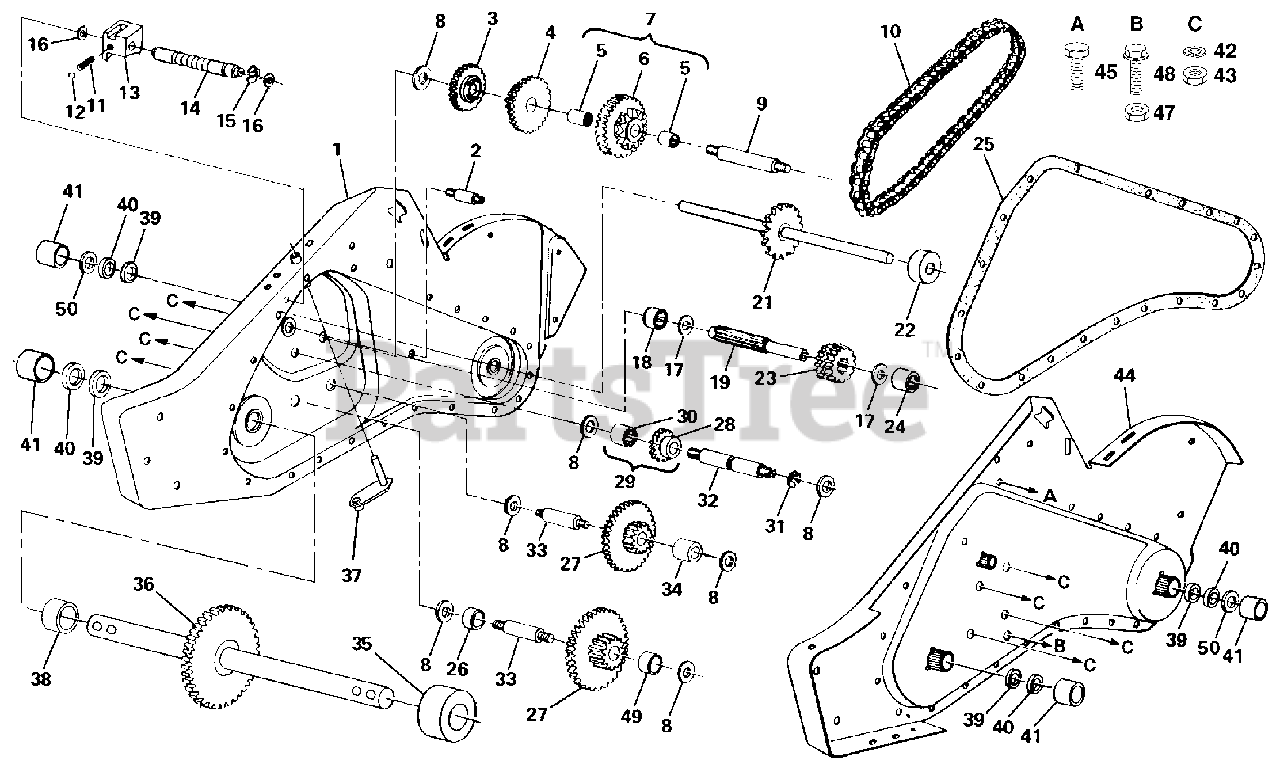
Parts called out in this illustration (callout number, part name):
1	Gearcase Assembly, R.H., with Bearing
2	Bolt, Upset
3	Gear, Reverse
4	Gear, Cluster, Red., 1st and 2nd
5	Bearing, Needle
6	Sprocket Assembly, Tine
7	Sprocket Assembly with Bearings
9	Shaft, Reduction, 1st
10	Chain, Roller, 60P
11	Spring, Shift, Fork
12	Ball, Steel
13	Fork, Shift
14	Shaft, Shift
16	Washer, Seal
17	Race, Bearing, Thrust, 5/8 I.D.
18	Bearing, Needle
19	Shaft, Input
21	Shaft Assembly, Tine
22	Spacer 1.008 x 1-3/4 x .645
23	Pinion, Input
24	Bearing, Needle
25	Gasket, Gearcase
26	Spacer .765 I.D. x 1.12 x 5/8
27	Gear, Cluster, Red., 2nd and 3rd
28	Gear, Reverse Idler
29	Gear Assembly, Reverse Idler
30	Bearing, Needle
32	Shaft, Reverse Idler
33	Shaft, Reduction, 2nd
34	Spacer .765 I.D. x 1-1/8 x 1-3/8
35	Spacer, Ground Drive, L.H.
36	Shaft Assembly, Ground
37	Arm Assembly, Shift
38	Spacer, Ground Drive, R.H.
39	Seal, Oil
40	Seal, Ring, Rubber
41	Cup, Formed
42	Washer, Lock 7/16
43	Nut, Hex 7/16-20
44	Gearcase Assembly, L.H., with Bearing
45	Screw, Thd Cut 5/16-18 x 5/8
47	Nut, Hex Head 5/16-18
48	Screw, Whiz-Lock 5/16-18 x 4
49	Spacer .765 I.D. x 1.12 x 3/4
50	Ring, Spiral
